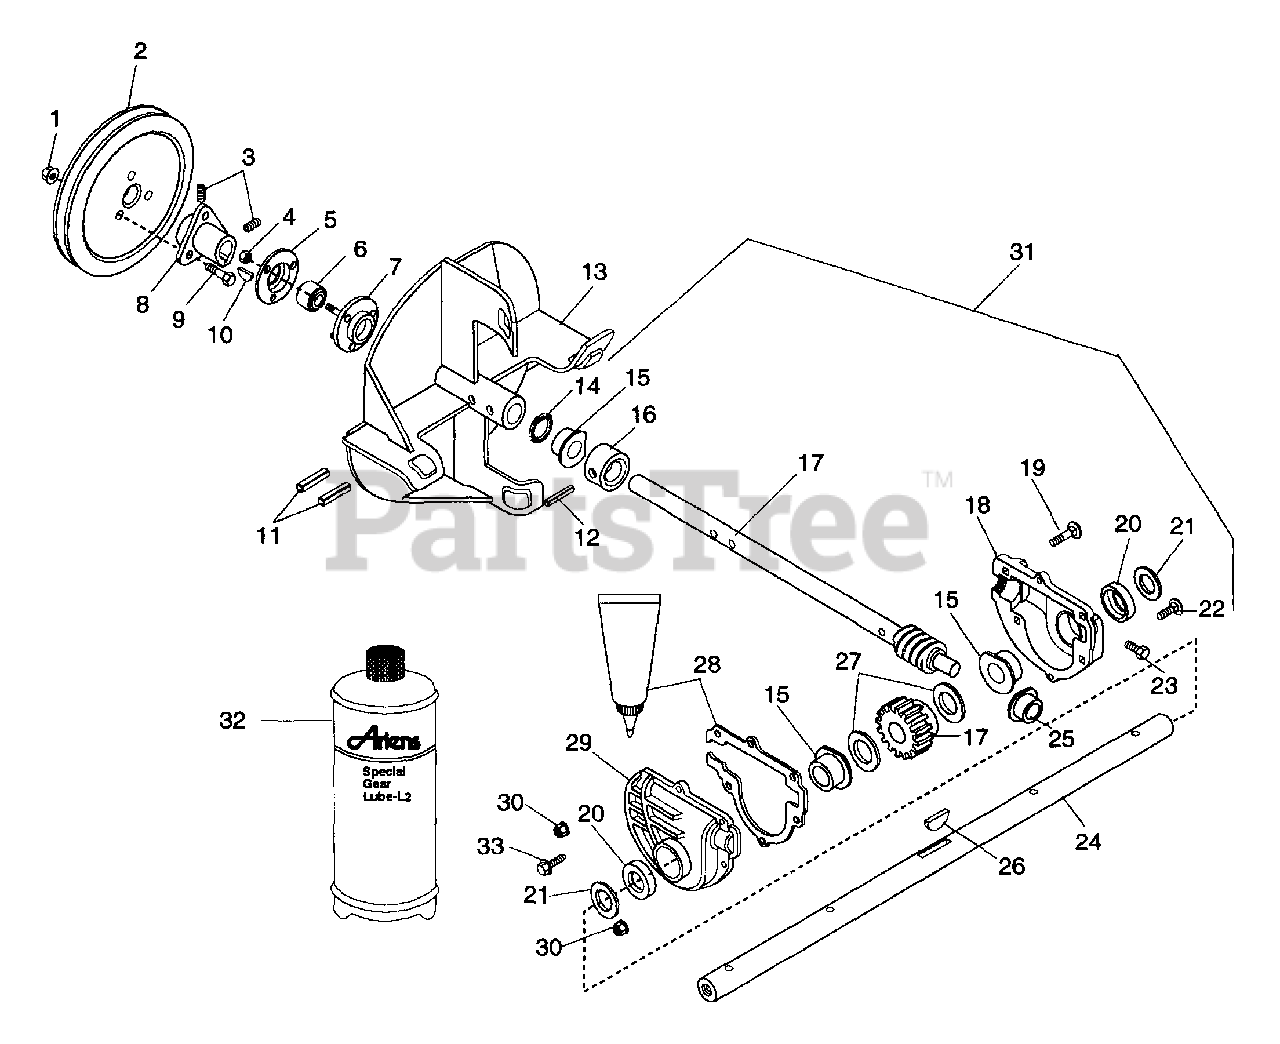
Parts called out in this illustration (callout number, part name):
1	NUT-FLG. .312-18 PL
2	PLY-V 8.50 X 1.25 3BLT
2	PLY-V 7.0 X 1.25 3 BLT
2	SHEAVE - IMPELLER
3	SCR-SET .31-18X.38 SKHCUPDL
4	NUT-LK-CTR .250-20 PL
5	BEARING FLANGE
6	BRG-BALL .750X1.750X.50
7	BEARING FLANGE
8	HUB
9	BLT-SERRDHD SL .31-18X.75 YZ
10	KEY-WDRF .188X.875X.375 SAE11
11	PIN-ROLL .250X1.25
12	PIN-GRV .188X1.25 TP A
13	IMPELLER - 10"
14	SEAL .750X1.00X.156
14	SEAL .750X1.000X.150
15	BSHG-FLG .750X1.000X.750X1.250
16	THRUST COLLAR
17	SHAFT AND WORM GEAR ASSEMBLY
18	L. H. GEAR CASE
18	GEAR CASE-LH-SMALL BORE
19	BLT-RDHDSQNK .25-20X1.25 GR5PL
20	SEAL .750X1.000X.125
21	WSHR-FL-STL.812X1.500X.139
22	BLT-RDHDSQNK .25-20X.88 PL
23	SCR-TAP .375-16X .50 HWH PL TR
24	SHAFT, RAKE - 20"
24	SHAFT, RAKE - 24"
25	BSHG-FLG .500X.750X.750X1.000
26	KEY-WDRF .188X.625X.25 SAE 61
27	WSHR-HDND-THRST .755X1.40X.062
28	GASKET
28	LOCTITE 518 GASKET--6ML TUBE
29	R. H. GEAR CASE
29	GEAR CASE-RH-SMALL BORE
30	NUT-LK-FLG .250-20 PL
31	GEAR CASE - 20" - ALUMINUM
31	GEAR CASE - 24" - ALUMINUM
32	BOTTLE ONLY-S.SCREEN.FOR NO.80
33	SCR-TAP 10-24X.75 HWH PL TR
